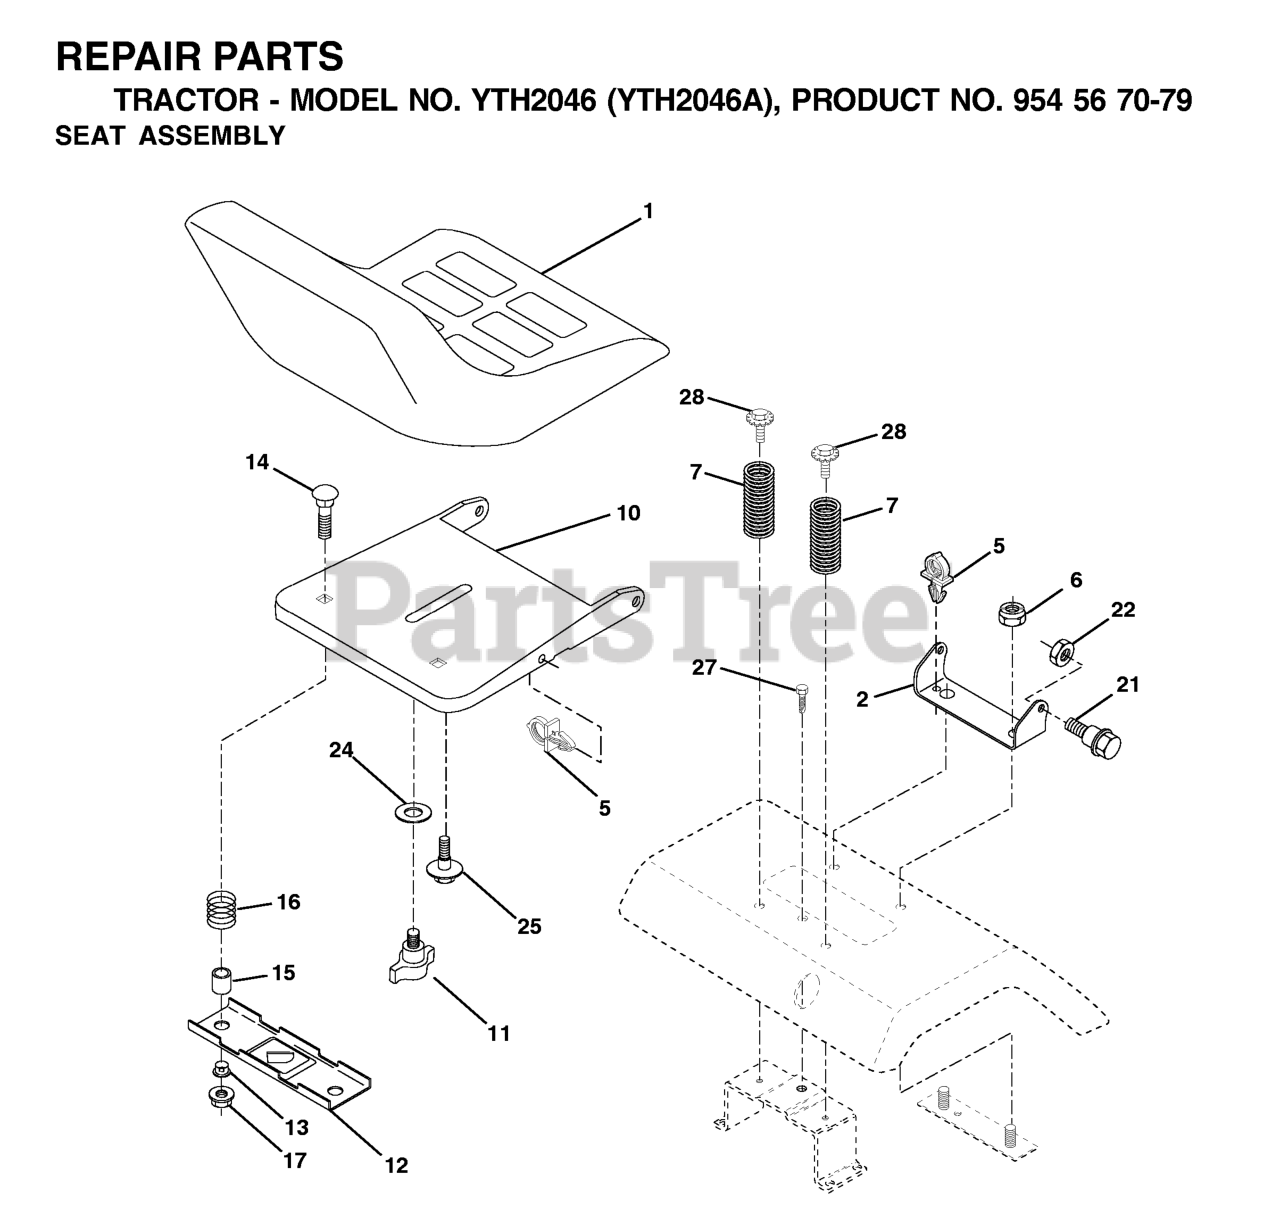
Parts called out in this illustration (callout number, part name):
1	SEAT, GRAY
2	SEAT PIVOT BRKT
3	BOLT
6	NUT
7	SPRING COMPRESSION
8	SCREW THDROL 3/8-16 X 1-1/2
9	WASHER
10	PAN, SEAT
11	KNOB.SEAT.ADJ.WINGNUT
12	BRKT SWITCH
14	BOLT.ROUND.HEAD.SQUARE.NECK
15	SPACER SPLIT
16	SPRING COMPRESSED
17	NUT T
18	CAP SPRING
21	BOLT.SHOULDER.5/16-18
22	NUT.71038.31-18.HEX.NYLOCK
25	BOLT,SHOULD
28	BOLT.5/16-18UNCX3/4 W/SEMS.BLK
